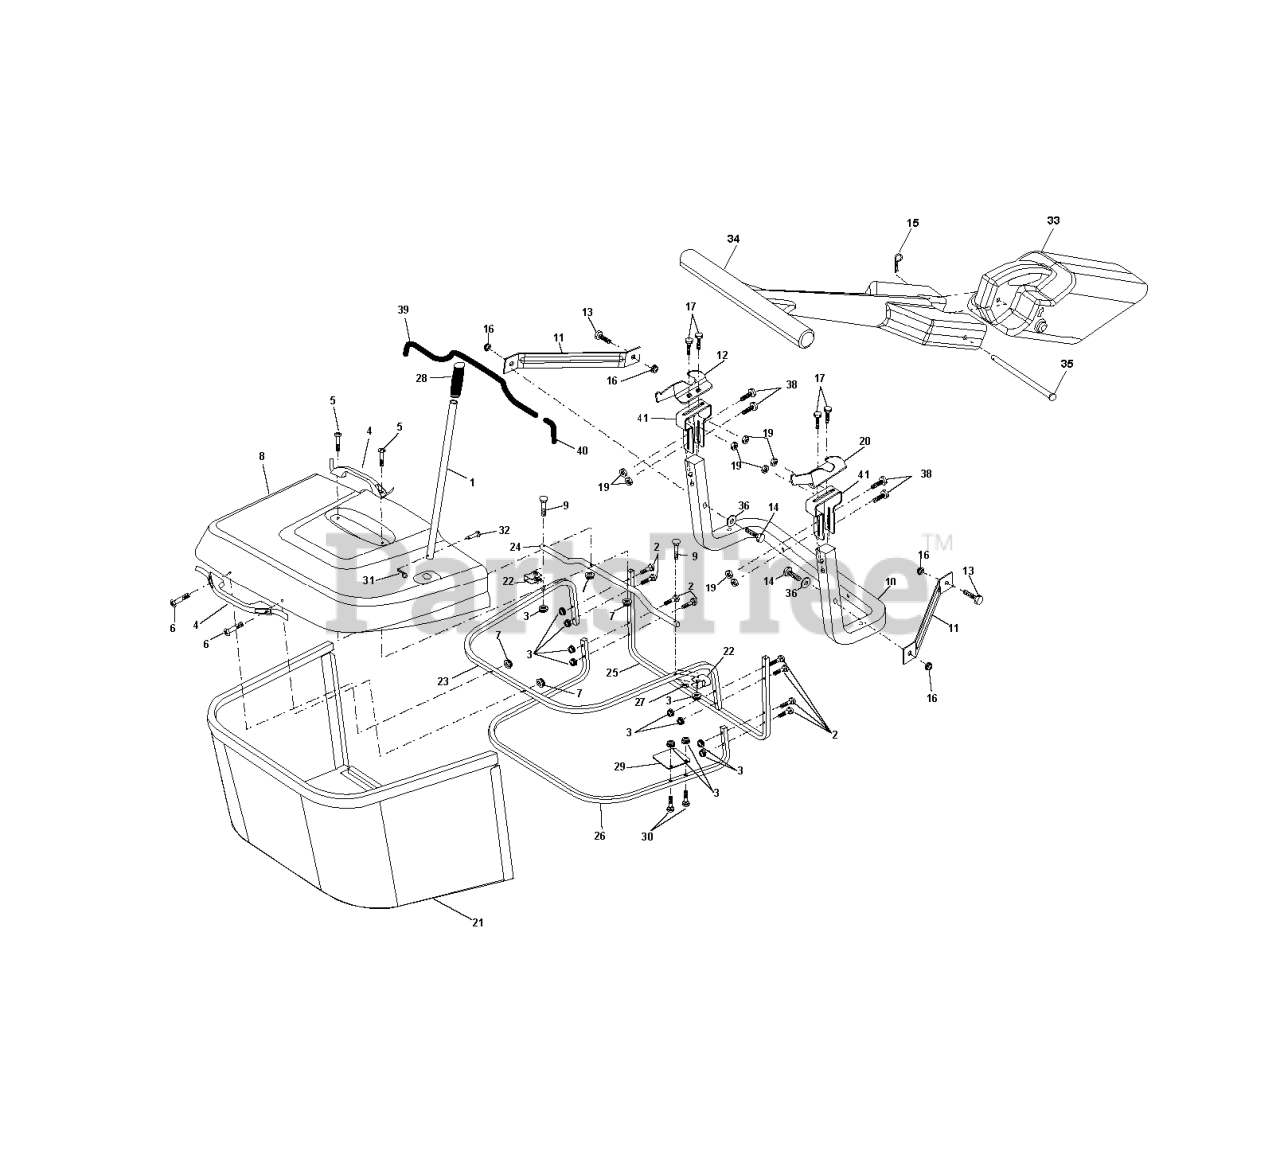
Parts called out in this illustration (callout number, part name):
1	TUBE HANDLE
2	Bolt Carriage 1/4-20 x 2.0 Gr.5
3	NUT T
4	HANDLE.BAGGER.W/LVRS.BLK.CRD
5	SCREW.PAN.HEAD
6	REPL BY 532 75 00-29
8	COVER
9	Bolt Carriage 1/4-20 x 2.25d x Gr.5
10	TUBE
11	BRACKET.SUPPORT.UPPER.BAG.CRD
14	Bolt Hex 3/8-16 x 2-1/2 Gr. 5
15	RETAINER-SPRNG RB
16	NUT LOCK FLG 3/8-16 UNC
17	RP BOLT 5/16-18 X3/4 ZN/YEL GR
18	WASHER M
19	NUT.71038.31-18.HEX.NYLOCK
20	BRACKET
21	BAG
22	BRKT.SIDE.BAG.CRD
23	TUBE.UPPER.BAG.CRD
24	TUBE.PIVOT.BAG.CRD.BLACK
26	TUBE.LOWER.BAG.CRD
28	GRIP.HANDLE.BLACK
30	Bolt Carriage 1/4-20 x 1 Gr.5
31	RETAINER M
32	RIVET,DRILLED
33	MULCH PLUG, CTH150
34	HANDLE.MULCHER.92.CRD (2 2)
36	WASHER
38	BOLT.5/16-18X2.5
39	TRIM
40	TRIM
41	BRKT.VERT.ADJ.BAGGER.CRD
